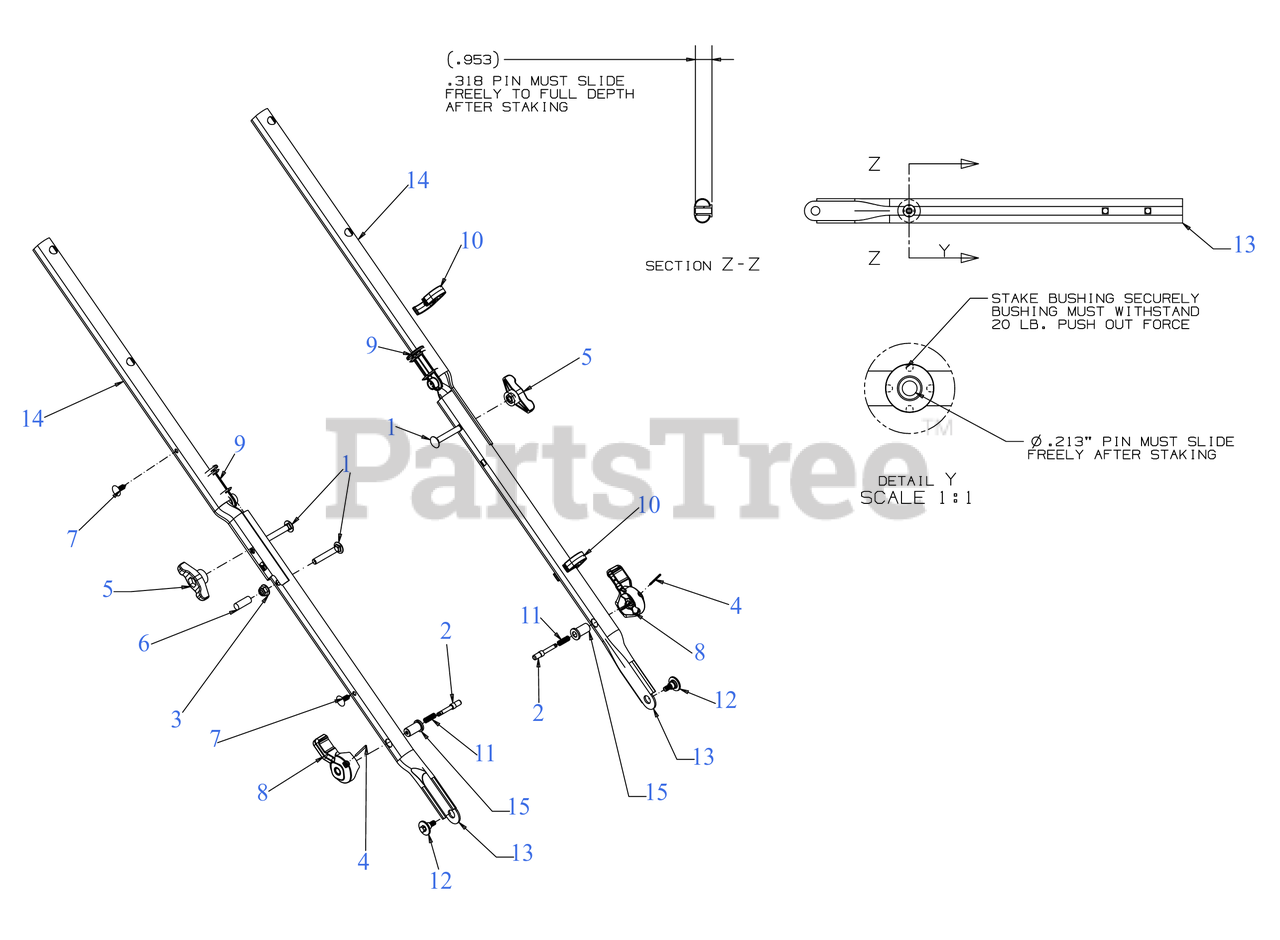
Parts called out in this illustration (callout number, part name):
1	BOLT 5/16-18 x 2.00 GR5
2	HANDLE ADJUSTMENT PIN
3	FLANGE LOCK NUT 5/16-18
4	SPLIT ROLL PIN 5/64 x 1.38
5	WING KNOB 5/16-18
7	RATCHET CLIP .250
8	HANDLE LEVER KNOB
9	HANDLE END PLUG
10	CABLE CLIP CORE
11	COMPRESSION SPRING
12	SHOULDER SCREW .500 x .118X1/4-20
13	LOWER HANDLE
14	UPPER HANDLE CORE
15	HANDLE ADJUSTMENT SPACER
